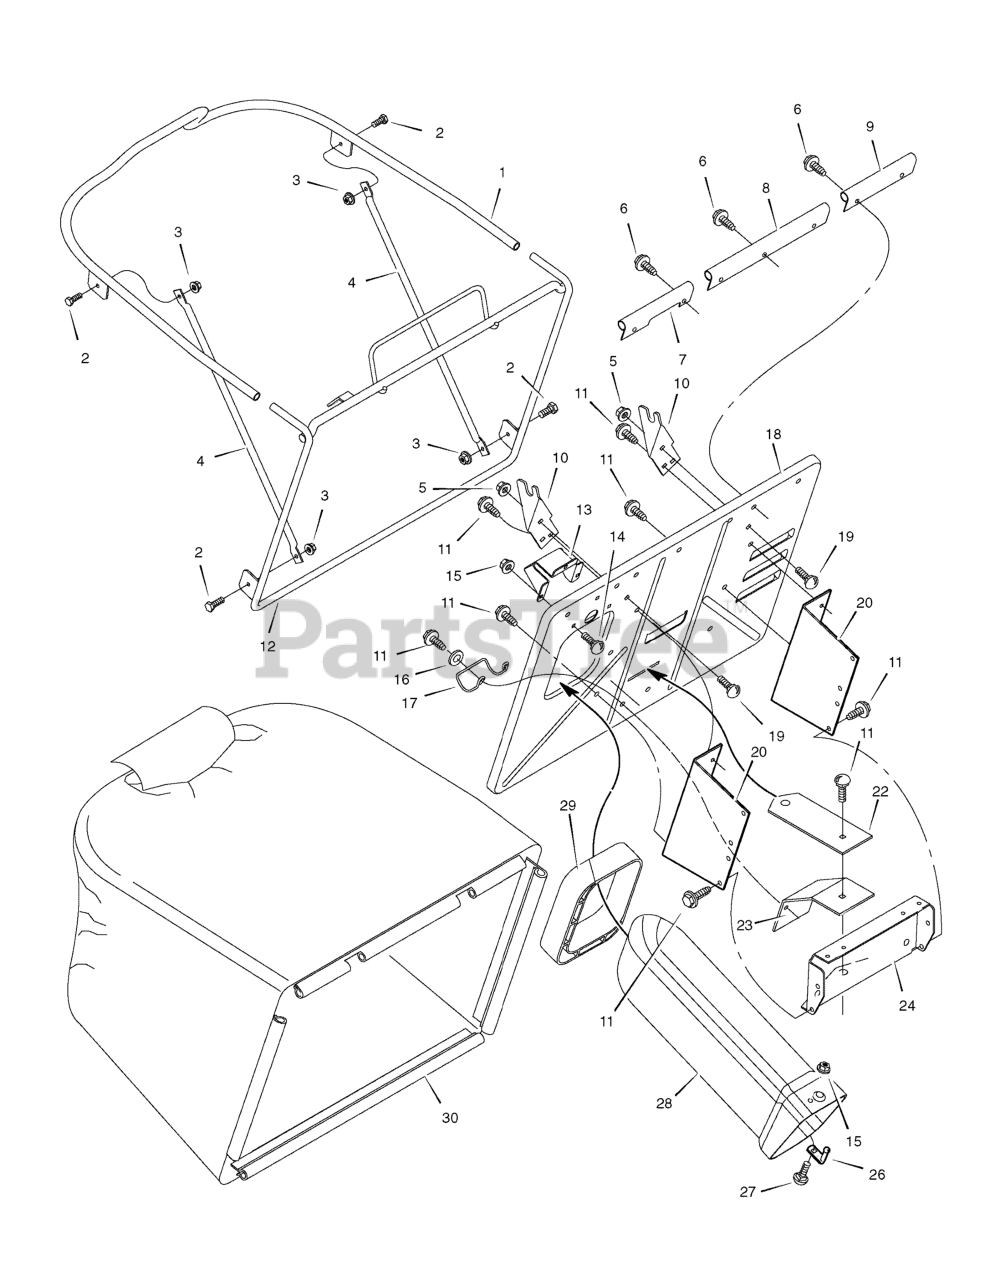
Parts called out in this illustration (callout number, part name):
1	Tube, Top
2	Bolt
3	Nut
4	Strut, Bag
5	Nut, Flange
6	Fastener, Panel
7	Seal, Bag (Right End)
8	Seal, Bag (Center)
9	Seal, Bag (Left End)
12	Assembly, Bag Frame
13	Bracket, Switch
14	Bolt, Carriage
15	Nut, Flange
16	Washer
17	Latch, Spring
19	Bolt, Carriage
20	Bracket, Bagger Mounting
22	Plate, Hitch
23	Bracket, Lower Mounting
24	Plate, Hitch
26	Pin, Latch
27	Bolt, Carriage
28	Tube, Connecting
29	Grommet, Extension Tube
30	Bag, Grass
